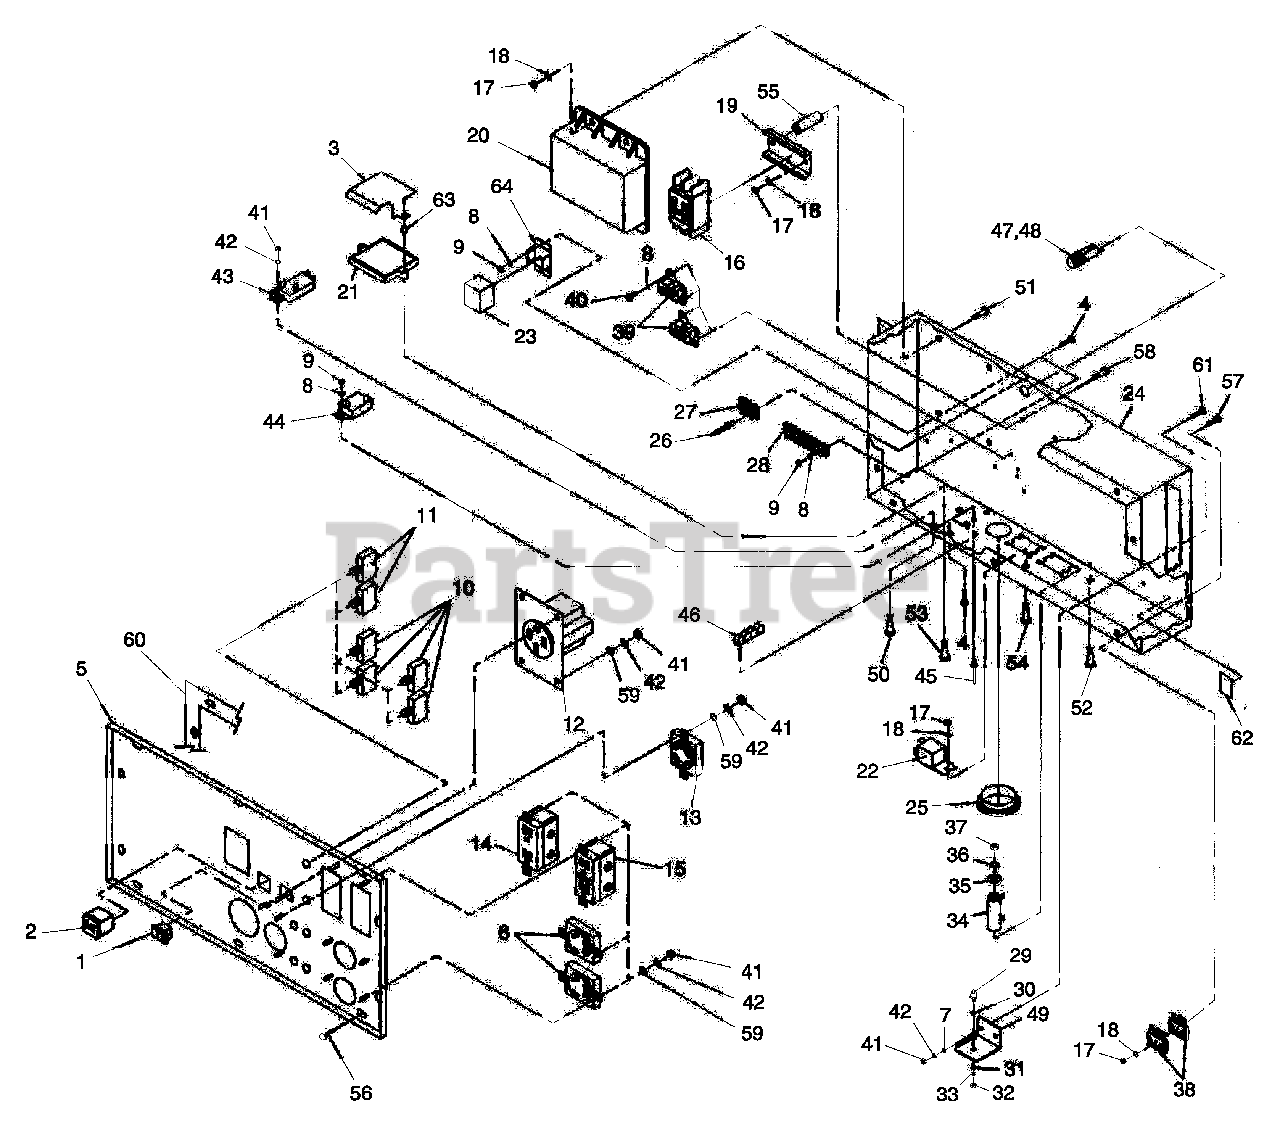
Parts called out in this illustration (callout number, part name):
1	SWITCH, ROCKER -/0
2	OUTLET, 12VDC SNAP
3	COVER, GOVERNOR CONTROL
4	SCREW PPHM M3-0.5 X 12
5	PANEL, SHEET METAL
6	OUTLET 30A 120V RECEPT
7	WASHER FLAT #6
8	WASHER LOCK M3
9	NUT HEX M3-0.5 G8
10	CIRCUIT BREAKER 30A
11	CIRCUIT BREAKER 20A
12	OUTLET 50A 125/250V
13	OUTLET 30A 125/250V
14	OUTLET 20A 120V DPLX
15	OUTLET 20A 120V GFCI
16	CIRCUIT BREAKER 50A 400V 2POLE
17	NUT HEX M5-0.8 G8
18	WASHER LOCK #10
19	DIN RAIL 59.5mm LONG
20	ASSEMBLY VOLTAGE REGULATOR 60HZ
21	ELECTRONIC GOVERNOR / IDLE CONTROLLER
22	RELAY PNL 12VDC SPST 30A
23	RELAY 3PDT 12VDC
24	CONTROL PANEL BOX
25	BUSHING SNAP
26	RIVET POP .156 X .160-. 164 / #20
27	BLOCK TERMINAL 20A 2 X 6 X 1100V
28	BLOCK DOUBLE ROW TERMINAL 8 POSITION
29	RECTIFIER MSC 12A 600V
30	WASHER MICA .203
31	WASHER STEP NYLON .20
32	NUT HEX #10-32
33	WASHER FLAT #10
34	RESISTOR 25R 5% 25W
35	WASHER FLAT 1/4
36	WASHER LOCK M6-1/4
37	NUT HEX M6-1.0 G8
38	RECTIFIER-BATTERY CHARGER
39	TRANSFORMER, IDLE CURRENT
40	SCREW PPHM M3-0.5 X 8
41	NUT HEX M4-0.7 G8
42	WASHER LOCK M4
43	CIRCUIT BREAKER 6 X 1
44	CIRCUIT BREAKER 10 X 1 12VDC 1/4"QC
45	RIVET POP .125 X .129-. 133 / #30
46	LUG GRND 8 TABS
47	HOLDER FUSE
48	FUSE 10AX AGC10
49	HEATSINK
50	SCREW PPHM M4-0.7X 10
51	SCREW HHC M5-0.8 X 16 G8.8
52	SCREW HHC M6-1.0 X 65 G8.8
53	SCREW HHC M5-0.8 X 25 G8.8
54	SCREW HHC M5-0.8 X 10 G8.8
55	SPACER .25 X.50 X 1.5
56	SCREW HHTT M5-0.8X 10
57	SCREW PPHM M5-0.8 X 30
58	SCREW PPHM M5-0.8 X 50
59	WASHER FLAT #8
60	GASKET, PORTABLE CONTROL PANEL
61	SCREW PPHM M4-0.7X 16
62	TAPE ELEC UL PERMACEL
63	NUTTRIC M5-0.8
64	RELAY BASE 3PDT 12VDC
